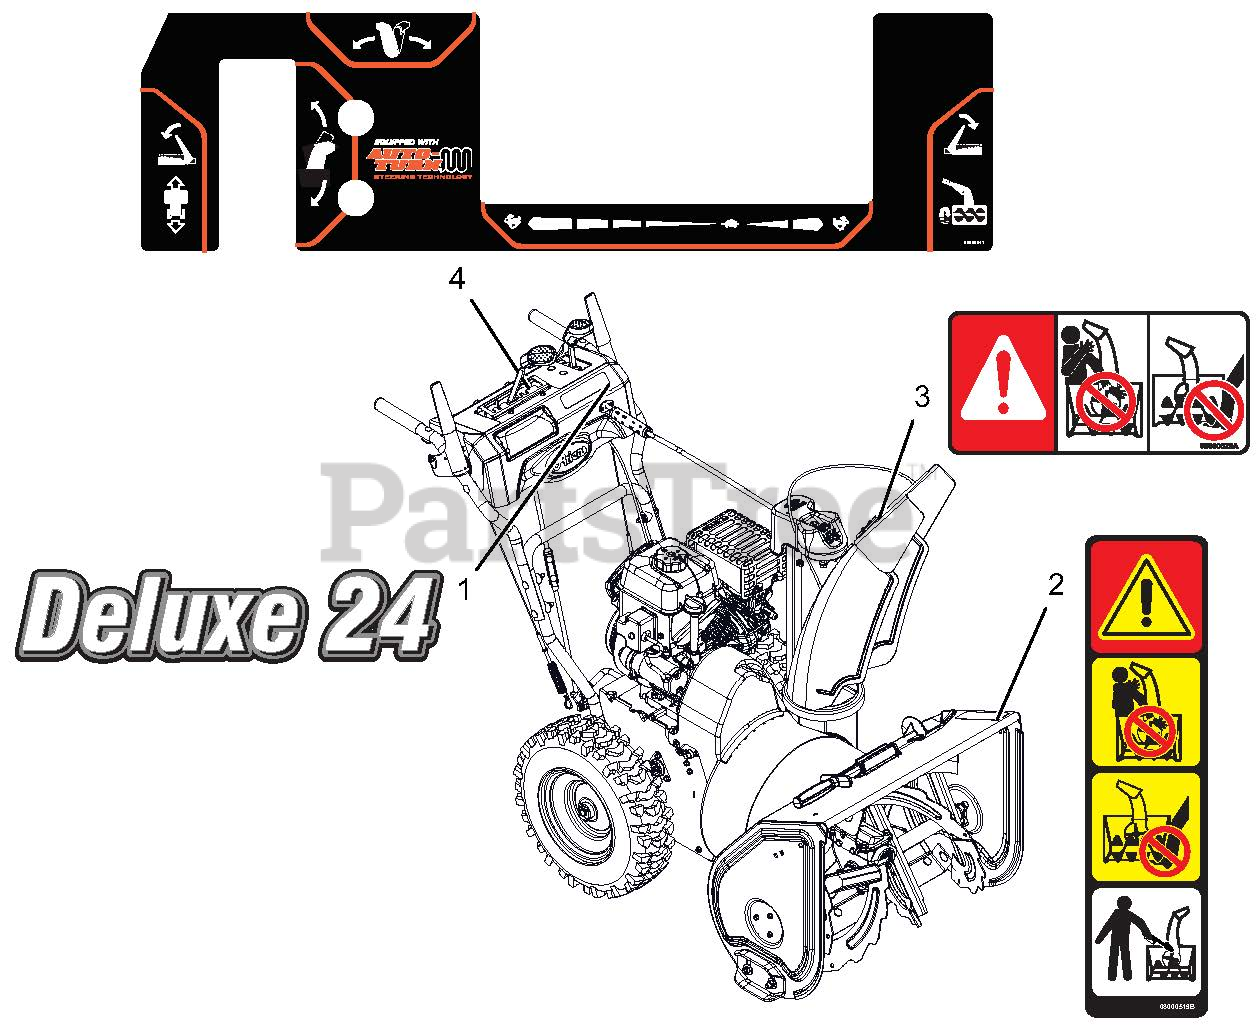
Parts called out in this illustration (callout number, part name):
1	DECAL,ST24 DELUXE-COMPACT DASH
2	DECAL, DANGER - ROTATING PARTS
3	DECAL, DANGER
4	DECAL,CONTROL-SML,AT,ID
